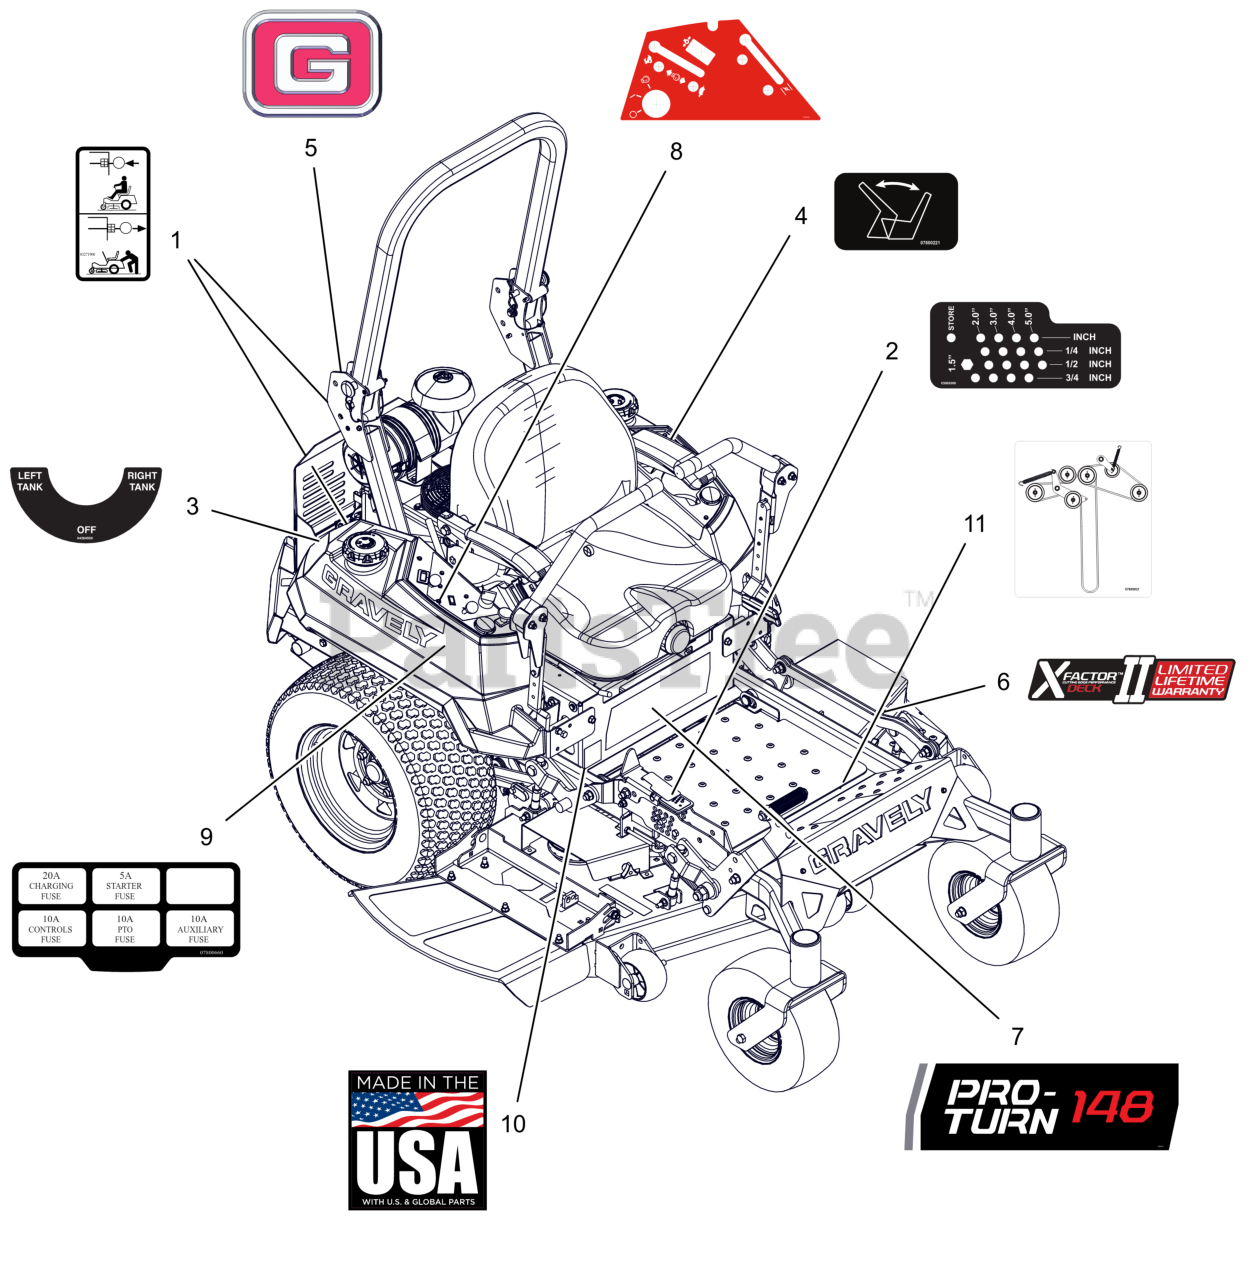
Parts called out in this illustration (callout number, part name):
1	DECAL, TRANSMISSION DISCONNECT
2	DECAL, HEIGHT OF CUT
3	DECAL, FUEL VALVE
4	DECAL - SEAT RELEASE
5	DECAL, GRAVELY BRAND
6	DECAL, X-FACTOR DECK
7	DECAL, PRO-TURN 148
8	DECAL, NON-EFI CONTROL PANEL
9	DECAL, FUSE BLOCK
10	DECAL, MADE IN USA
11	DCL,BELT ROUTE-RH V-SIDE IDLER
